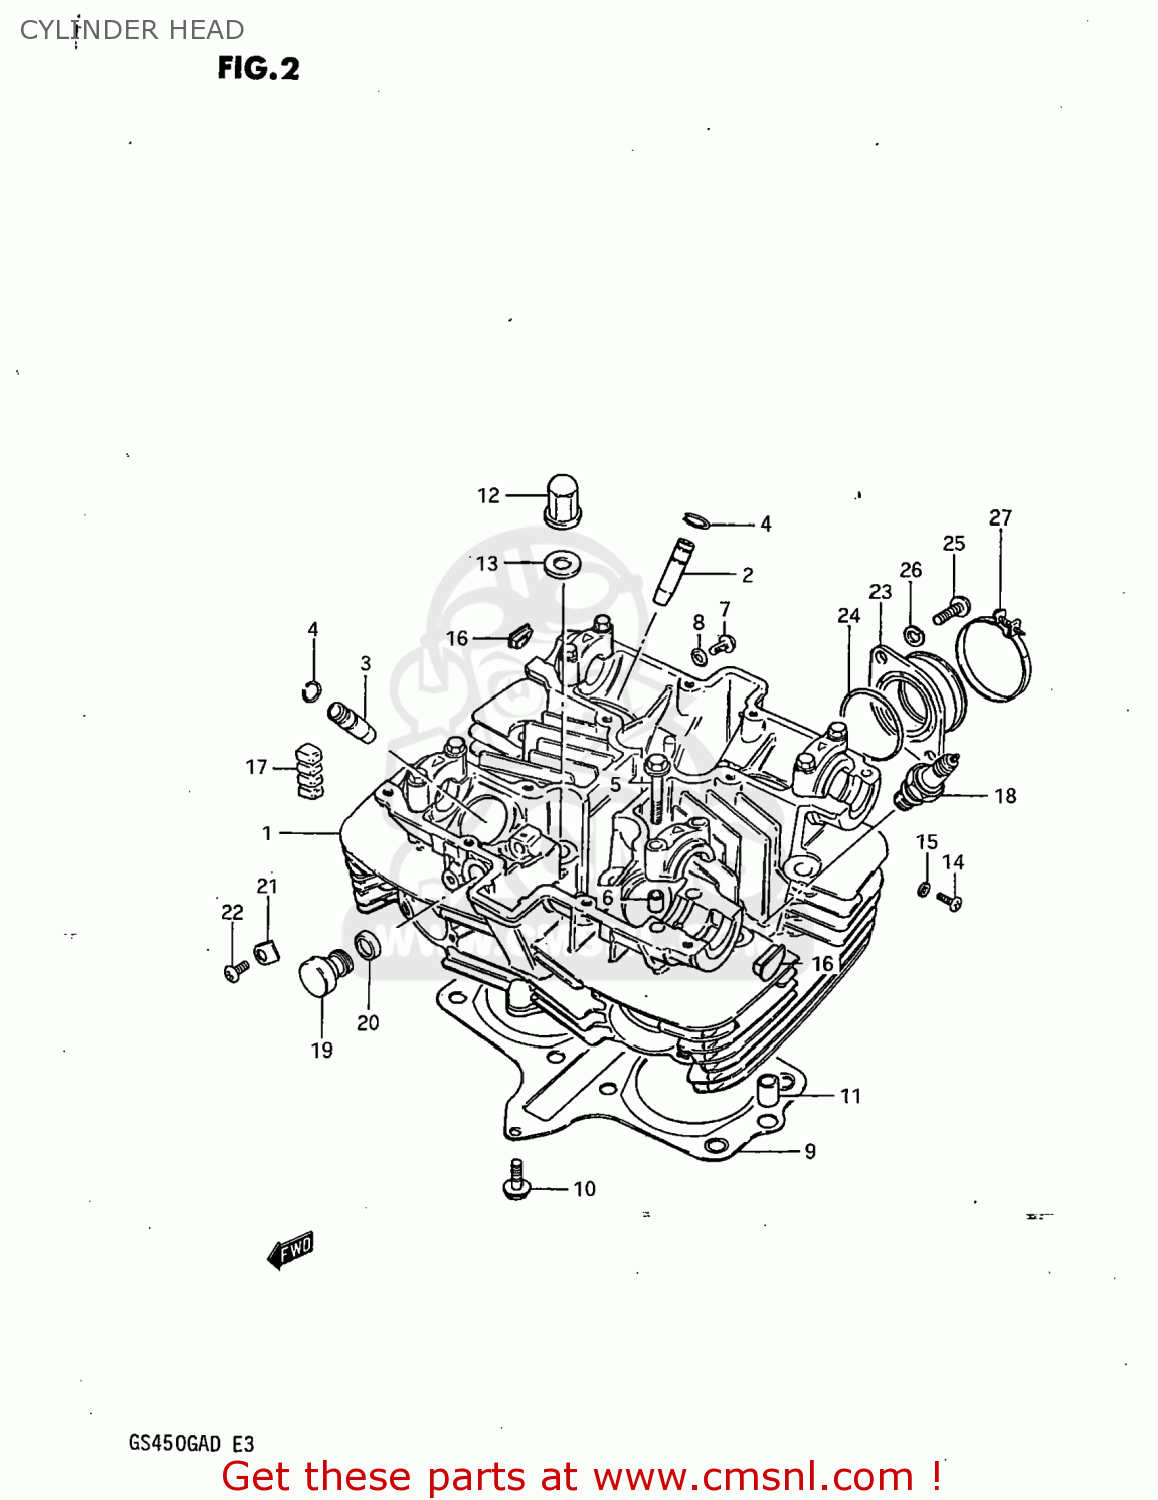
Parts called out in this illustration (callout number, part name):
1	HEAD ASSEMBLY,CYLINDER
2	GUIDE,INTAKE VALVE
3	GUIDE,EXHAUST VALVE
4	RING,SNAP
5	BOLT(6X39)
6	PIN(6.2X8X11)
7	BOLT
8	WASHER
9	GASKET,CYLINDER HEAD (MCA)
10	BOLT
11	PIN
12	NUT
13	GASKET(10.5X22X2) (NAS)
14	SCREW
15	GASKET(5.3X9.3X1.2) (NAS)
16	PLUG
17	PAD,CYLINDER
18	PLUG,SPARK
19	PLUG,TACH GEAR SLEEVE HOLE
20	SEAL,TACHOMETER DRIVEN
21	PLATE,TACH DRIVE GEAR SLEEVE
22	SCREW(5X12)
23	PIPE,INTAKE
24	O-RING (D:2.4 ID:39.7)
25	SCREW
26	LOCK WASHER
27	CLAMP
